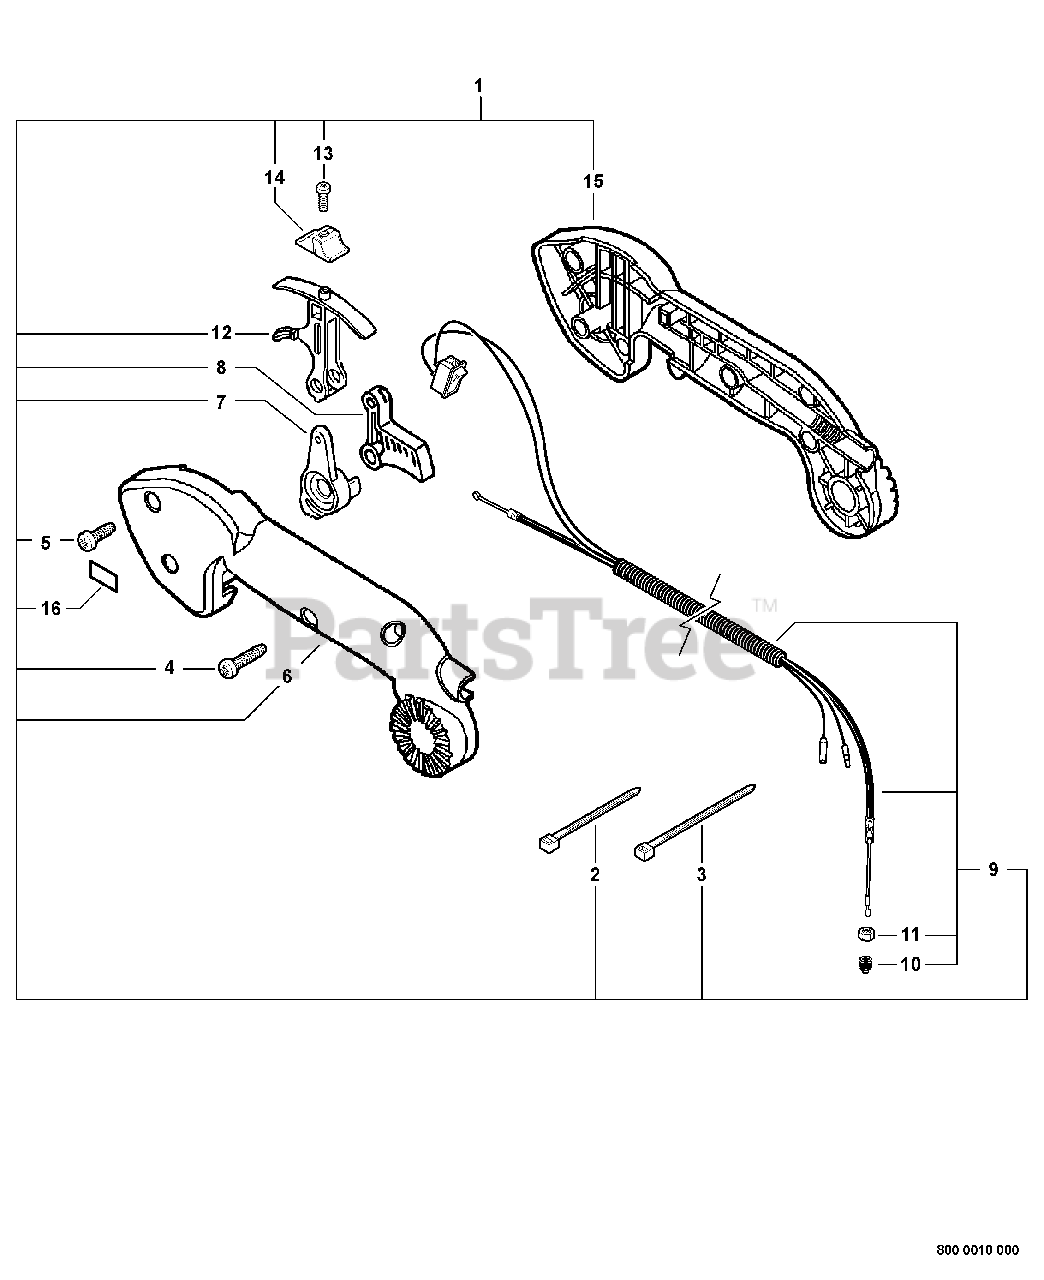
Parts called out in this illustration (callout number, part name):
1	CRUISE CONTROL KIT
2	TIE, CABLE - SMALL
3	TIE, CABLE - LARGE
4	SCREW - 5X20
5	SCREW - 5
6	HANDLE, FRONT - LEFT
7	LEVER, THROTTLE
8	TRIGGER, THROTTLE
9	CONTROL CABLE ASSY
10	CAP, DUST
11	LOCKNUT - 6
12	LEVER, THROTTLE CONTROL
13	SCREW - 3X14
14	KNOB, THROTTLE CONTROL
15	HANDLE, FRONT - RIGHT
16	LABEL - IDLE
